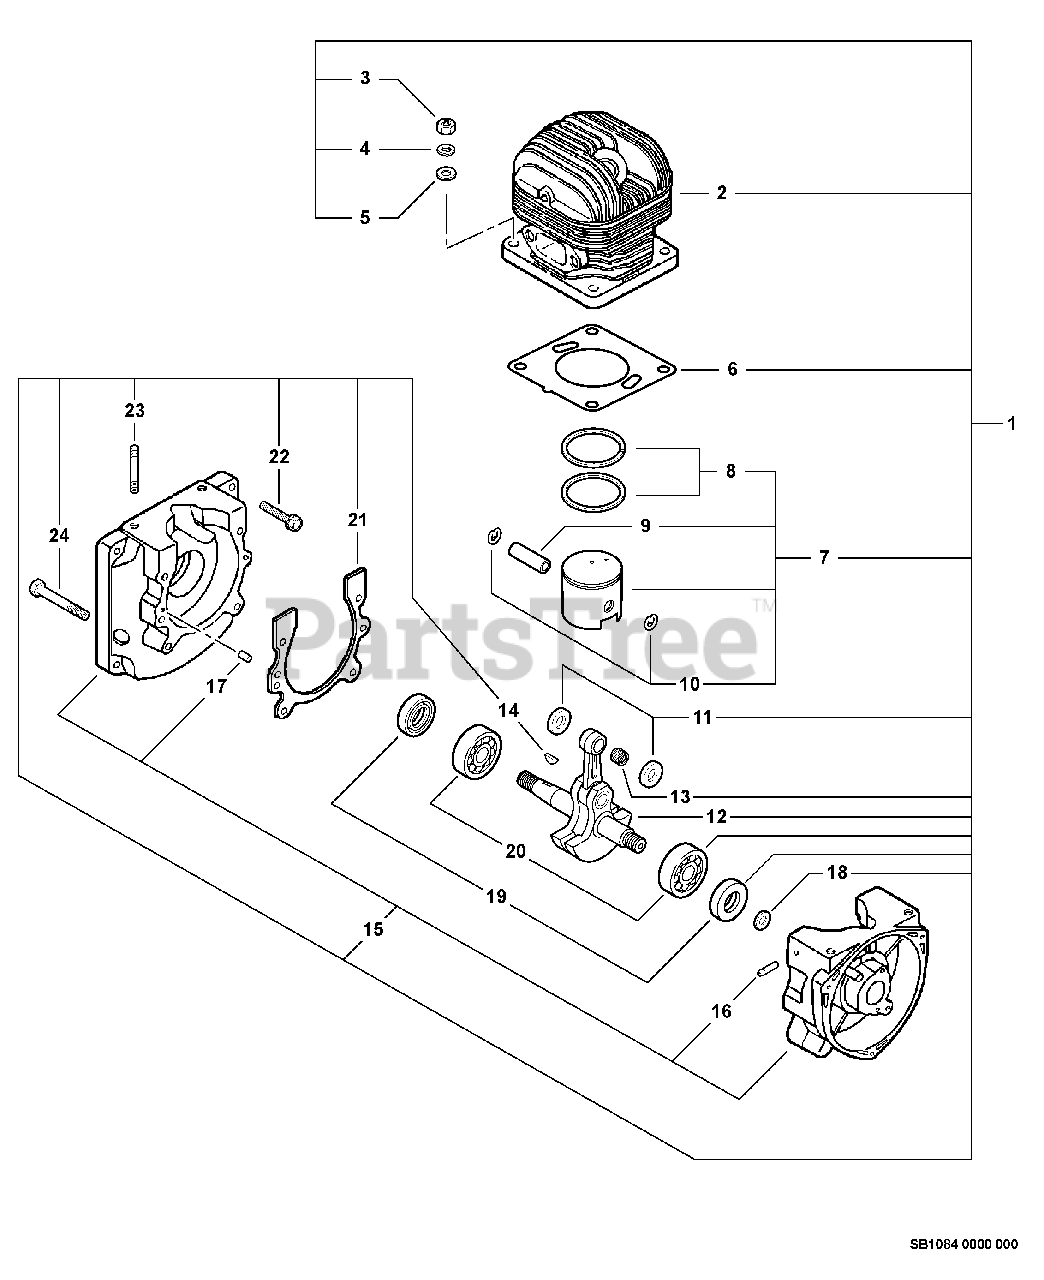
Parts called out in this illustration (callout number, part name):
1	SHORT BLOCK -- SB1084
2	CYLINDER
3	LOCKNUT - 6
4	LOCKWASHER - 6
5	WASHER - 6
6	GASKET, CYLINDER
7	PISTON KIT
8	RING, PISTON
9	PIN, PISTON
10	RING, RETAINING - 8
11	SPACER, PISTON
12	CRANKSHAFT ASSY
13	BEARING, NEEDLE
15	CRANKCASE KIT
16	CONNECTOR
17	PIN - LOCATING
18	WASHER - 10
19	SEAL, OIL
20	BEARING, BALL - 6202
21	GASKET, CRANKCASE
22	BOLT - 6X25
